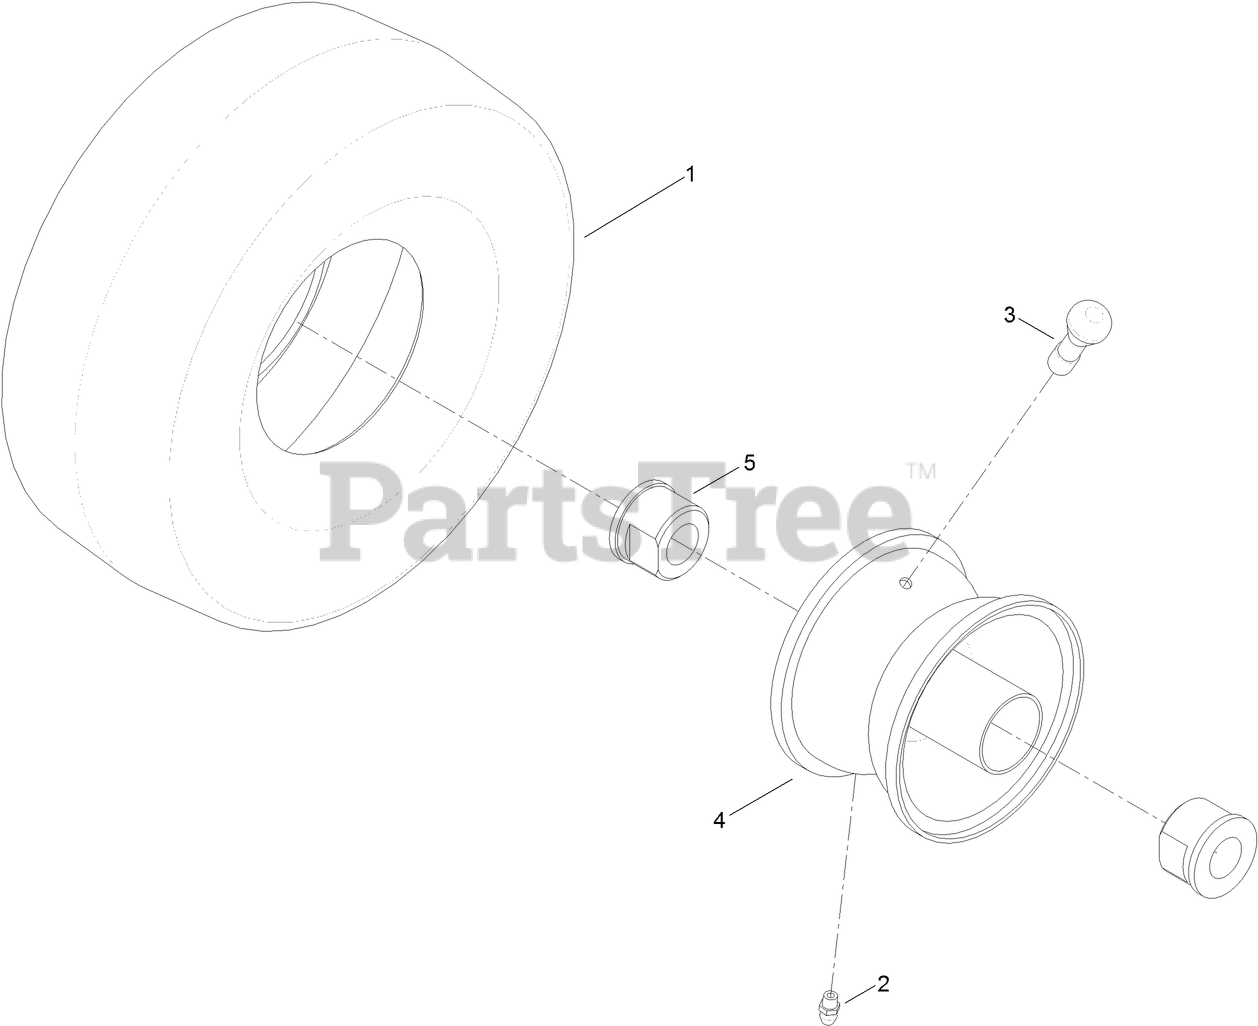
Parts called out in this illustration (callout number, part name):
1	TIRE-SMOOTH (CST)
2	FITTING-GREASE
5	BUSHING-FLANGE
